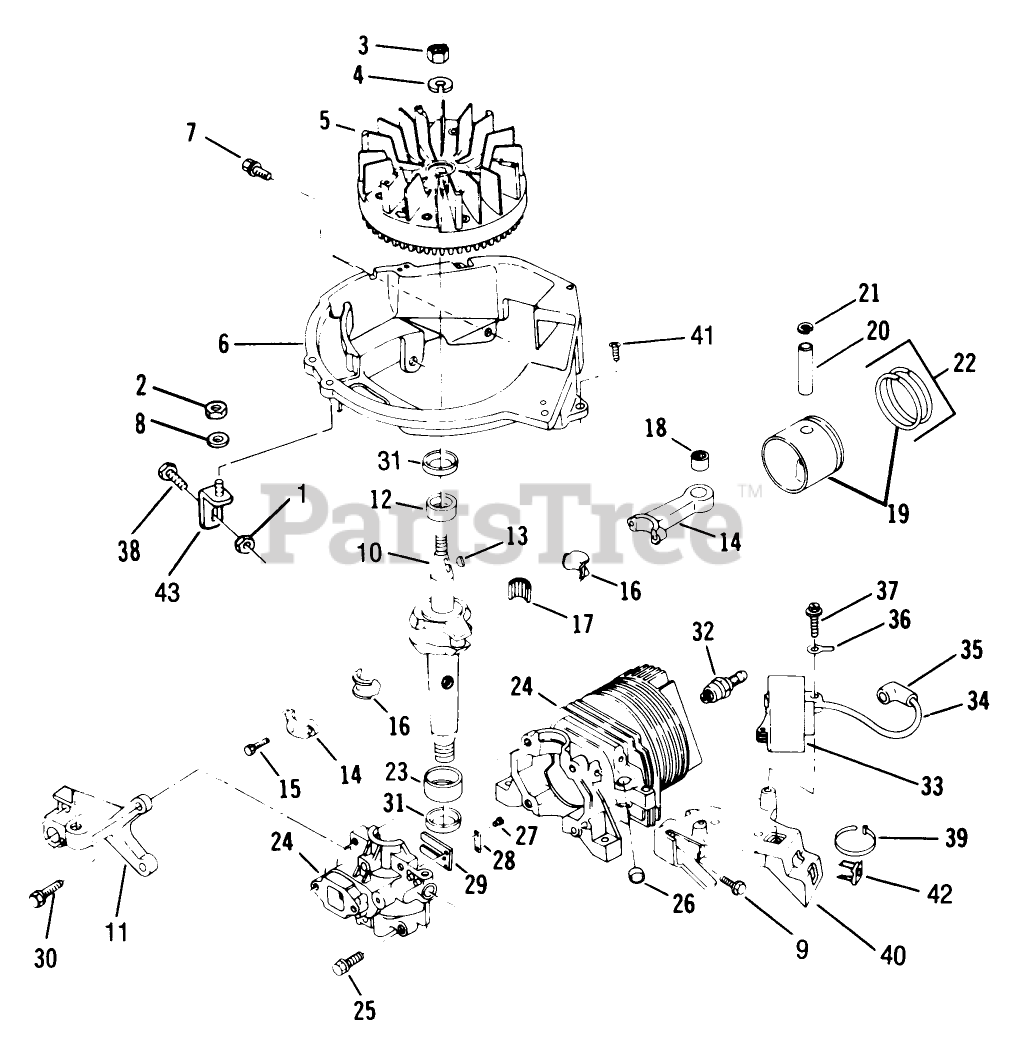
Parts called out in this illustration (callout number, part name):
1	NUT-LOCK F
2	LOCKNUT E
3	NUT
5	FLYWHEEL ASSY F
7	SCREW-SEMS
8	WASHER S
11	BRACKET-BRAKE F
12	BEARING V
13	KEY
15	SCREW-HSH
16	LINER ASM
17	BEARING-NEEDLE
18	BEARING AY F
21	RING-RETAINING
23	BEARING V
25	SCREW S
26	PLUG-CORE VF
27	SCREW-HH
28	PLATE-BACKUP, REED
31	SEAL-OIL
34	HT LEAD&COVER XEV
36	TERMINAL S
38	BOLT F
40	BRACKET S
41	SCREW F
42	NUT-CLIP
43	BRACE AY F
